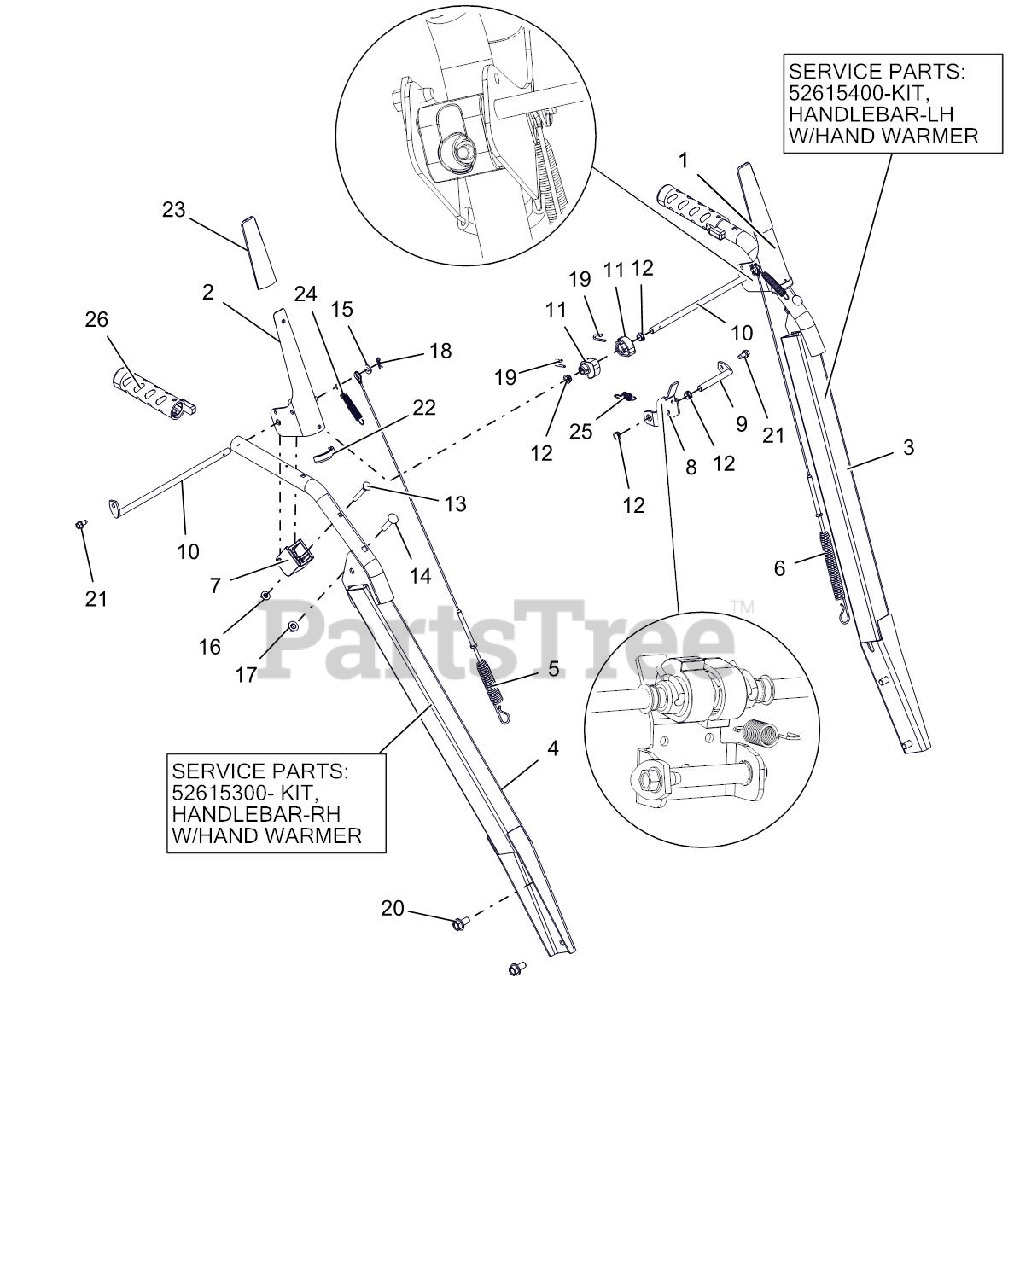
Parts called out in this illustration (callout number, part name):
1	LEVER, CLUTCH-LH
2	LEVER, CLUTCH-RH
3	HANDLEBAR, HEAVYDUTY-PRO LH
3	KIT, HANDLEBAR-LH W/WARM GRIP
4	HANDLEBAR, HEAVYDUTY-PRO-RH
4	KIT, HANDLEBAR-RH W/WARM GRIP
5	CABLE, AUGER (DELUXE & PRO)
6	CABLE, UPPER TRACTION
7	BLOCK, CLUTCH PADDLE
8	BRACKET, INTERLOCK ARM
9	ROD, PIVOT - INTERLOCK
10	ROD, PADDLE MOUNT - PRO
11	CAM, INTERLOCK
12	BUSHING, POLYLINER-.38 SNAPIN
13	BLT-RDHDXLSQNK .25-20X2.0 G5YZ
14	@BLT-RDHDSQNK .31-18X1.50 G5YZ
15	@WSHR-FL-STL.281X.62X.065 YWZC
16	@NUT-LK-CTR-FLG .25-20 YWZC
17	@NUT-LK-TOP-FLG .31-18 YWZC
18	PIN-HAIR INT .06X.18X.77
19	PIN, SPRING CLIP
20	BLT-SERHFWH .38-16X.75 YWZC
21	SCR-TAP .25-20X.50 HWH TR YWZ
22	EDGING, CLUTCH PADDLE - 2.00"
23	SLEEVE, CLUTCH PADDLE-GRAY
24	SPRING, EXTENSION
25	SPRING-EXT .047X.438X1.45
26	KIT, HANDWARMER - W/GLUE
